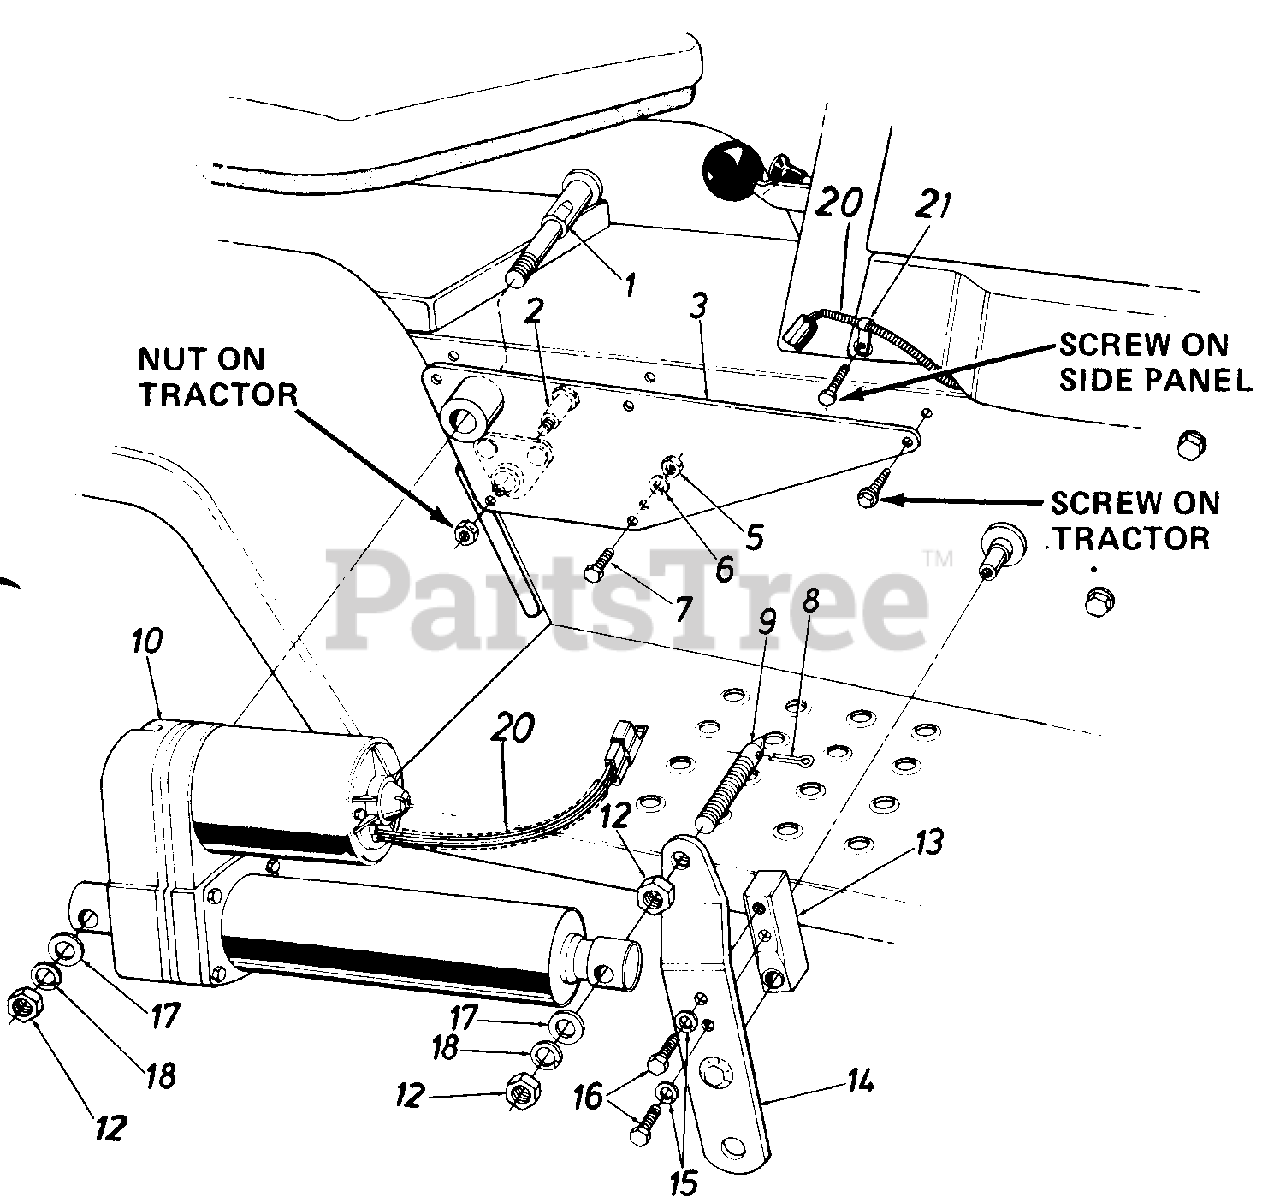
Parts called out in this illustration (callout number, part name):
1	Pivot Pin
2	Shld. Bolt.626 Dia. x .96"
6	L-Wash. 1/4" I.D.*
7	Hex Bolt 1/4-28 x .75" Lg.
8	Cotter Pin
9	Indicator & Mtg. Pin
10	Electric Actuator
12	Hex Jam Nut 1/2-13 Thd.
13	Lift Shaft Drive
16	Hex Bolt 5/16-24x 1.0" Lg.
17	Fl-Wash. .53" I.D. x.93" O.D.
18	L-Wash. 1/2" I.D.*
20	Plastic Tubing-7"
21	Clamp
